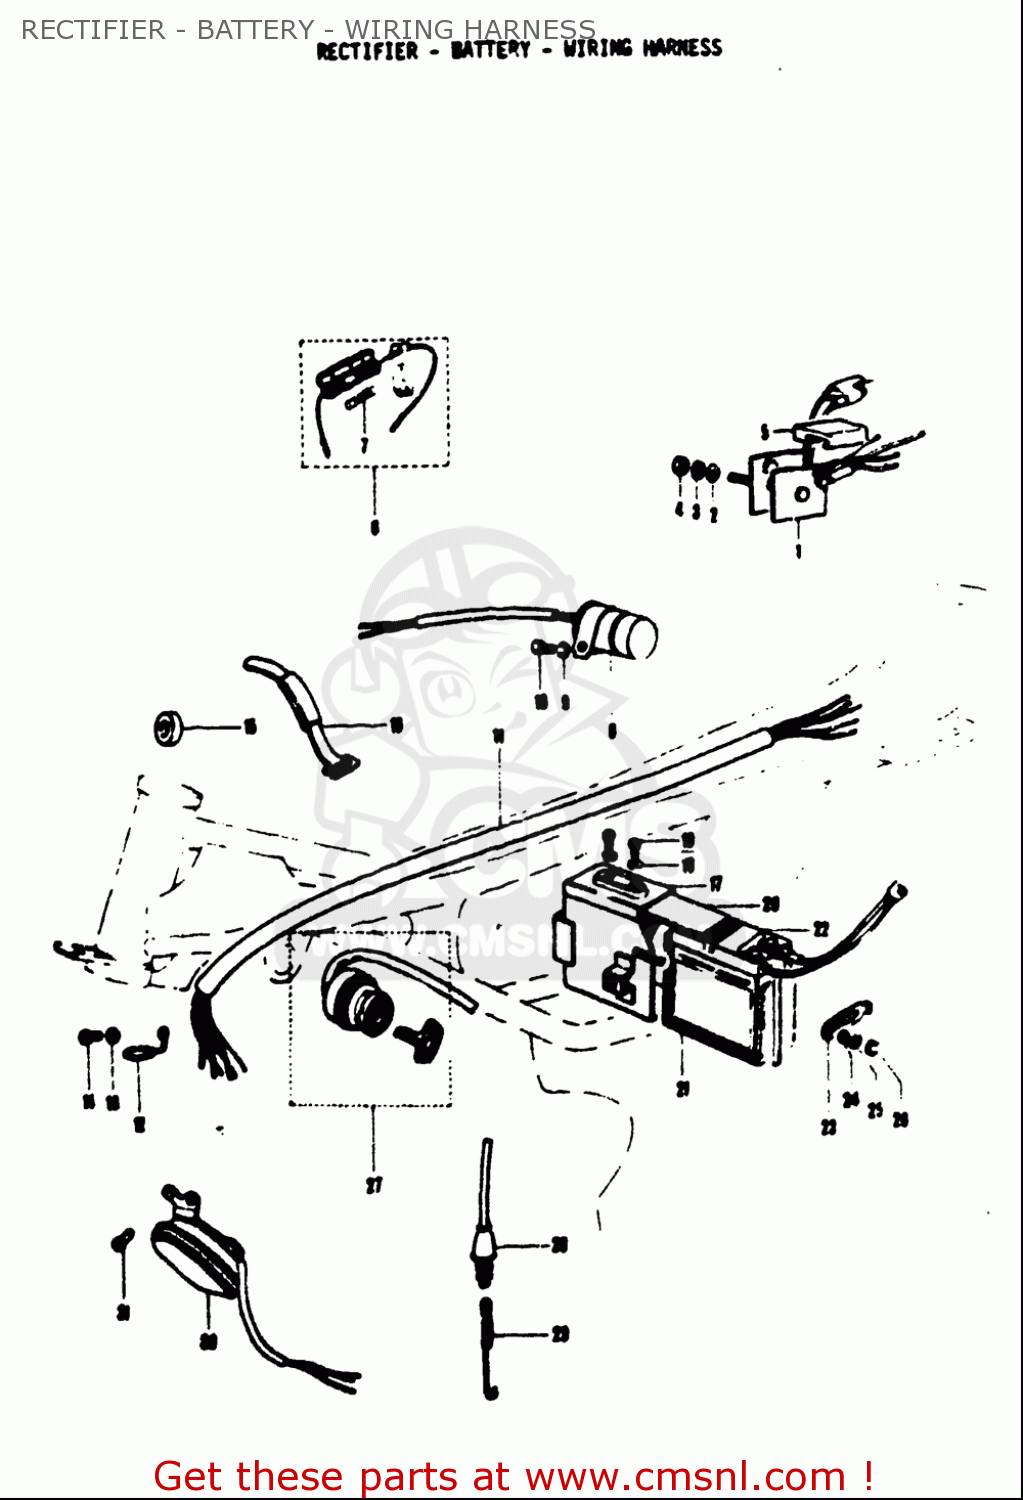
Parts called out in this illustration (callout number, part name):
1	RECTIFIER ASSY
2	WASHER
3	WASHER,LOCK
4	NUT
6	CASE ASSY,FUSE
7	FUSE(15A)
9	WASHER,LOCK
13	WASHER,LOCK
14	SCREW
18	WASHER,LOCK
24	WASHER
25	WASHER,LOCK
26	NUT
28	SWITCH,BRAKE LAMP
30	HORN ASSY
31	SCREW
